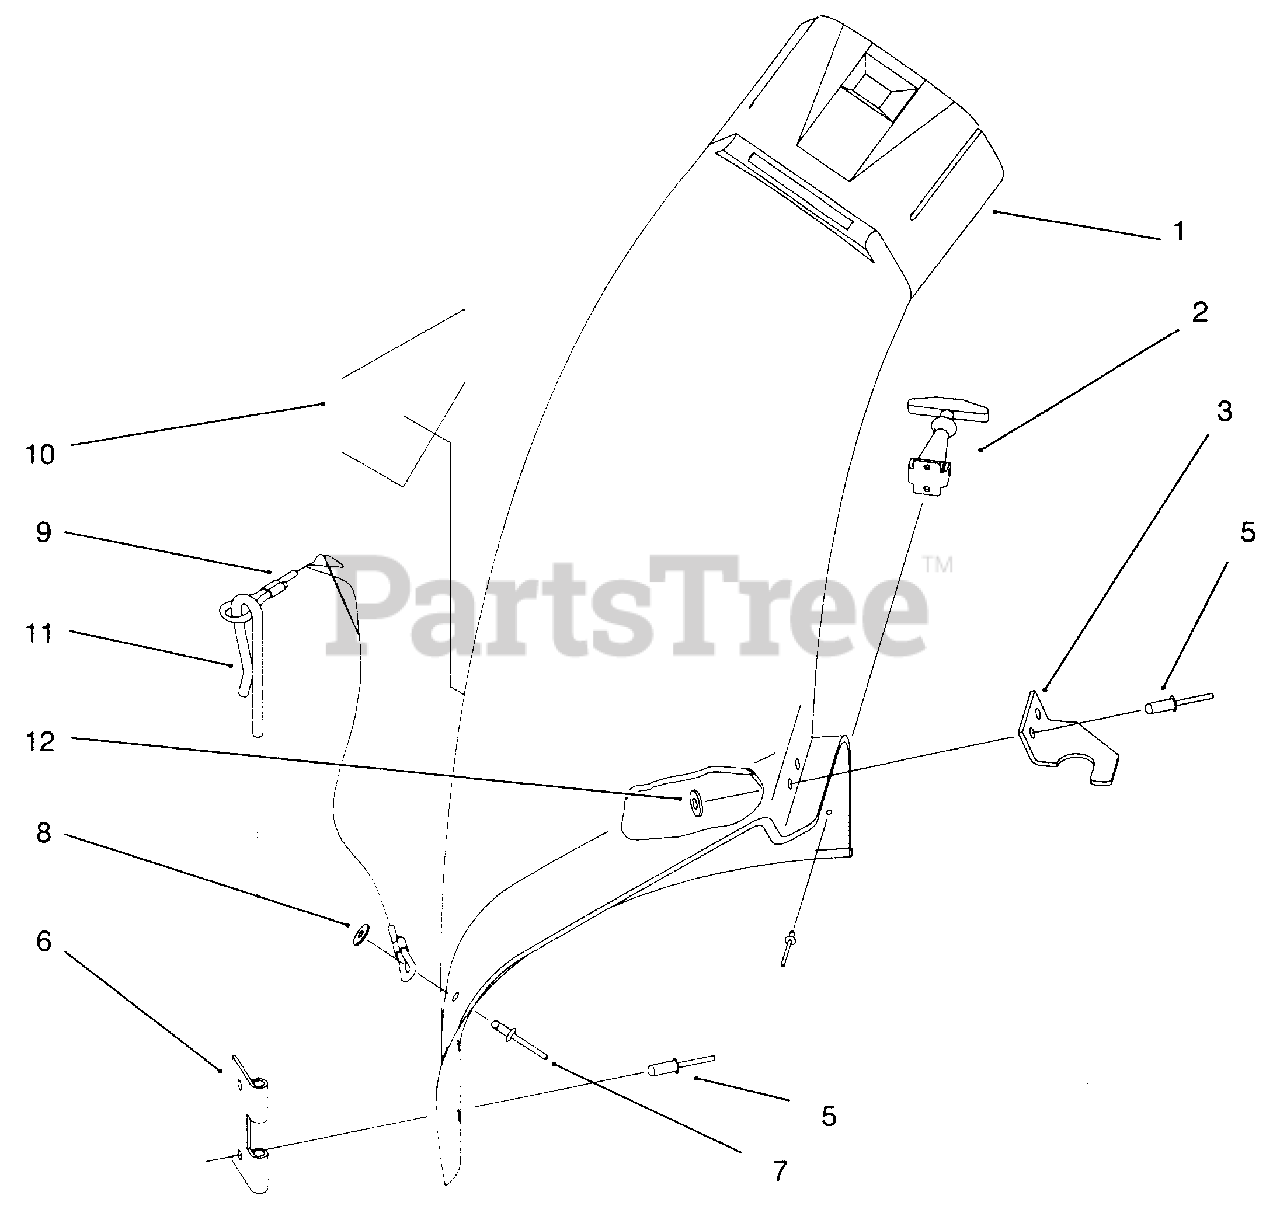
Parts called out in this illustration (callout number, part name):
1	Elbow-Bagger
2	Latch-Flexible Draw
3	Latch-Bagger Elbow
4	Rivet-Pop
5	Rivet-Pop
6	Bracket-Mounting Chute
7	Rivet-Pop
8	Washer-Flat
10	Decal-Danger
11	Pin-Lock, Chute
12	Washer-Flat
